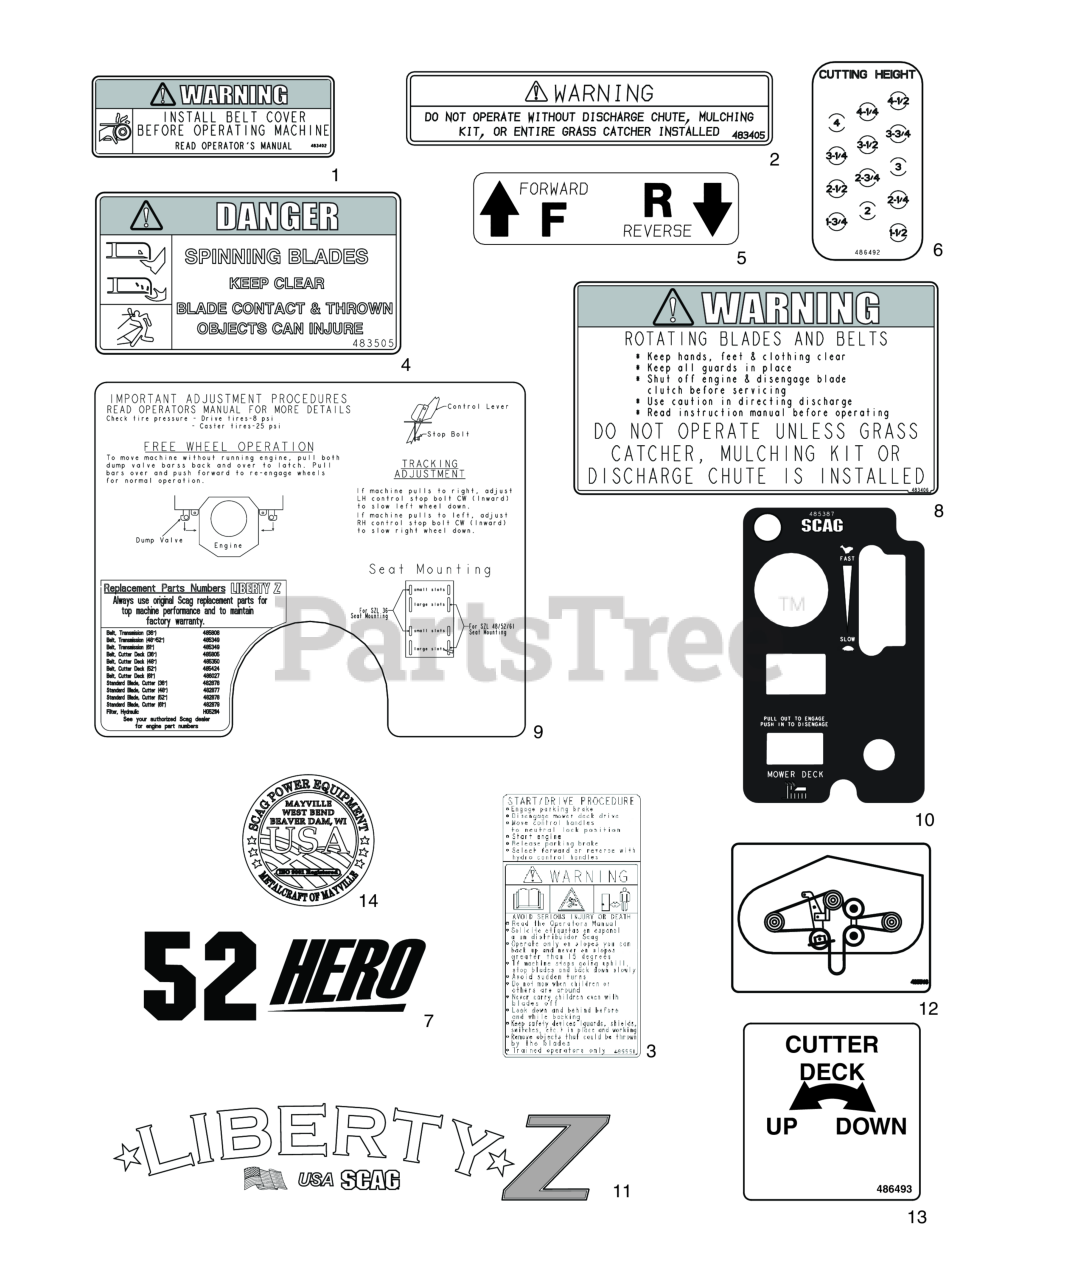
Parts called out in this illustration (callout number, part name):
1	Decal, Warning - Belt Cover
2	Decal, Warning-Discharge
3	Decal, Start/Drive
4	Decal, Spinning Blades
5	Decal, Traction Control
6	Decal, Height of Cut
7	Decal, 42 Hero
8	Decal, Warning - Rotating Blades
9	Decal, Adjustments - SZL
11	Decal. Liberty Z - Fuel Tank
13	Decal, Cutter Deck Lift Control
14	Decal, Metalcraft - USA
